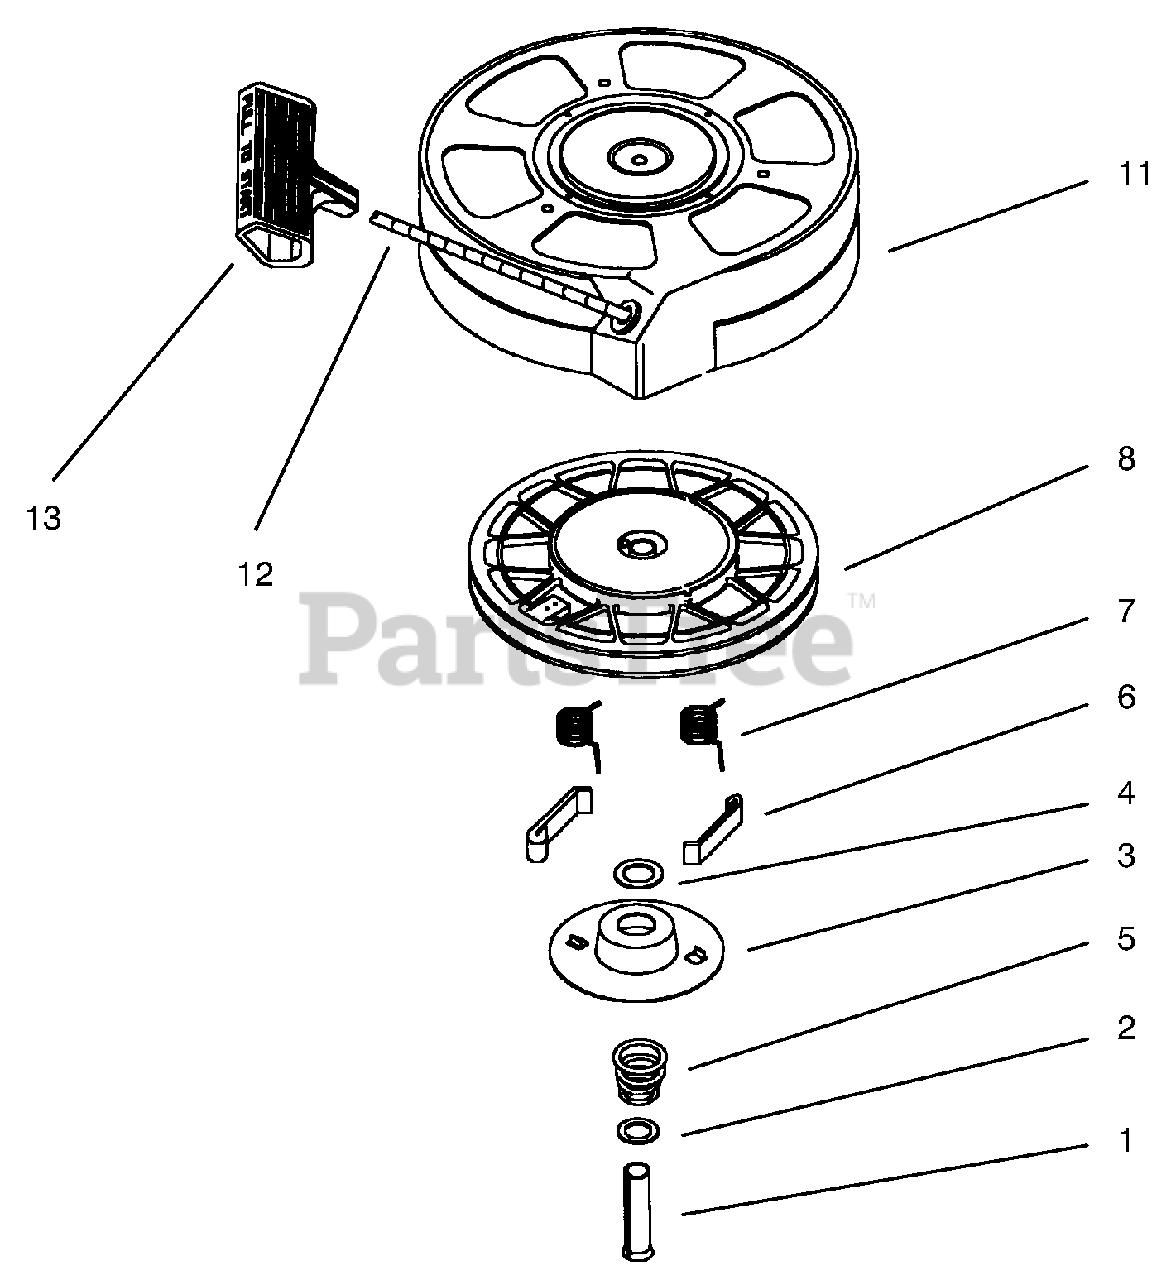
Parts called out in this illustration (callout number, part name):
1	Spring Pin (Incl. 4)
3	Retainer
5	Brake Spring
6	Starter Dog
7	Dog Spring
8	Pulley & Rewind Spring Ass'y.
11	Starter Housing Ass'y (40 degree grommet)
12	Starter Rope ( 98" X 9/64" dia.)
13	Starter Handle
